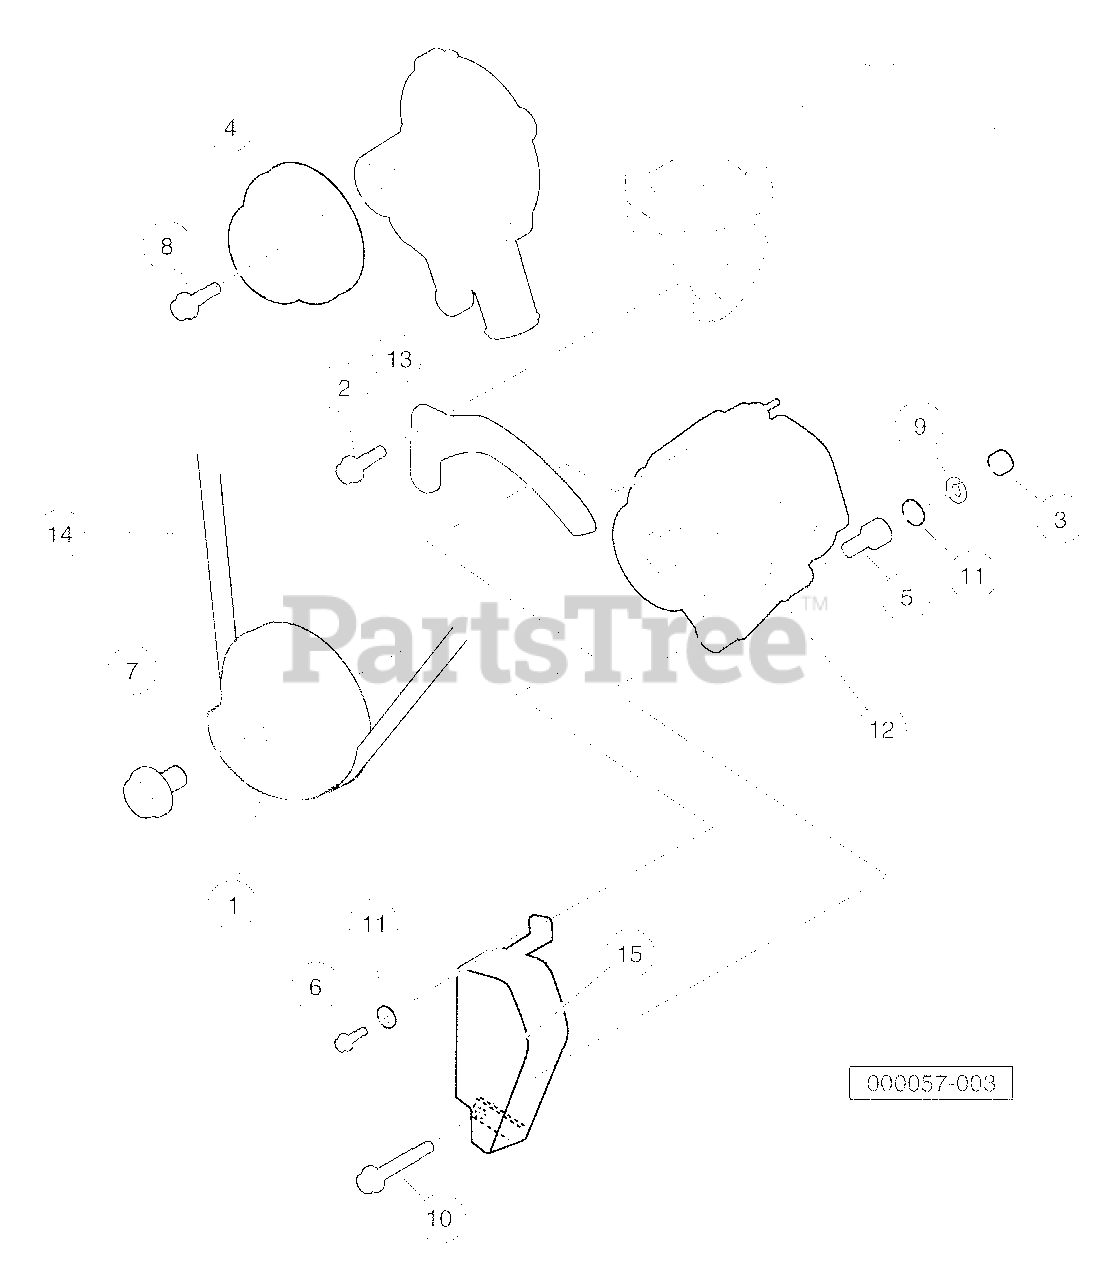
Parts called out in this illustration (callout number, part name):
1	Pulley, Fan Drive
2	Bolt, M6 X 1 X 20
3	Nut, M8, Plate
4	Pulley, Water Pump
5	Collar, Alternator Assy, D722
6	Bolt, Alt, D722, Adjuster
7	Bolt, Alt, D722, Drive Pulley
8	Bolt, D722, Drive Pulley
9	Washer, Spring, D722, Starter
10	Bolt, Alternator, Lower
11	Washer, Alternator, Upper
12	Alternator, 60 Amp
13	Brkt, Alt, D722, 60 Amp
14	Belt, Acc Drive, D722, 60 Amp
15	Guard, Acc Belt
